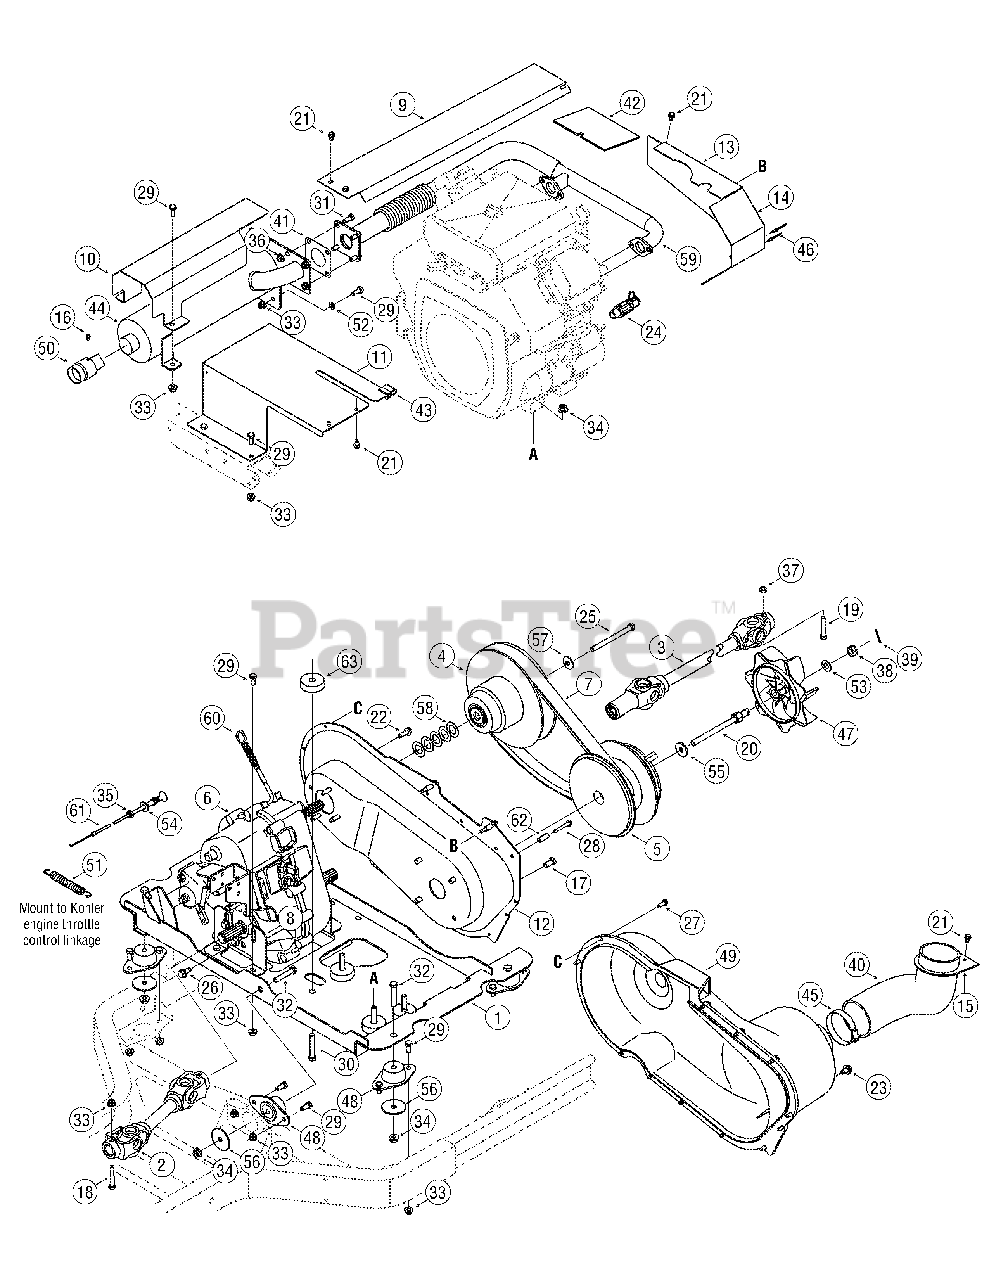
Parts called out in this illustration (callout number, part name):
2	Shaft Asm, Rr/prop
3	Shaft Asm, Frt/prop, Hilliard
4	Clutch Asm, Cvt, Driven
5	Clutch Asm, Cvt, Driver, Cvr
6	Case Asm, Transfer
7	Belt, Cvt, 4x4
9	Cover, Heat, Sheild
10	Exh, Shield, Heat
13	Cover, Eng, Kohler, Sealed Cvt
14	Cover, Engine, Rr, Kohler
16	Screw, F, #8-32, 0.375, Hxindwsh
17	Hex Screw, 3/8-16, .75, Gr5, Std
18	Hex Screw, 5/16-18, 2.00, Gr5, Patch
19	Hex Screw, 5/16-18, 1.875, Gr5, Patch
20	Hex Screw, 7/16-20, 5.00, Gr5, Special
21	Screw, Tt, 1/4-20, 0.500, Hxindwsh
22	Screw, Tt, 5/16-18, 1.000, Hxindwsh
22	Screw, Tt, 5/16-18, .750, Hxindwsh
23	Screw, B, 5/16-12, 0.500, Hxindwsh
24	Drain, Oil
25	Hex Screw, 3/8-24, 4.50, Gr5, Std
26	Screw, Tt, 3/8-16, 0.750, Hxindwsh
27	Screw, Tt, 1/4-20, 0.750, Hxindwsh
28	Screw, Tt, 1/4-20, 1.625, Hxindwsh
29	Hex Screw, 5/16-18, .75, Gr5
30	Hex Screw, 3/8-16, 2.25, Gr5, Std
31	Hex Screw, 5/16-18, .875, Gr5, Std
32	Hex Screw, 3/8-16, 2.00, Gr5, Std
33	Nut, Flglk, 5/16-18, Grf, Nylon
34	Nut, Flglk, 3/8-16, Grf, Nylon
35	Nut, Jam, 3/8-24, Gr5
36	Nut, Flglk, 5/16-18, Gr5, Sd Lk
37	Nut, Hexlk, 5/16-18, Grb, Ctrlk
38	Nut, Hex, 1/2-20, Gr5, Slot
39	Pin, Cot, 3/32, 1.0
40	Tube, Cvt, Intake
41	Gasket, Eng
42	Insl, Frame, Uv
43	Heat Baffle Seal
44	Muffler, Cat/khlr
45	Clamp, Hose, Adj, 2-3/4- 3-3/4
46	Rivet, Pop, .125 Od, #42
47	Impeller, Blo
48	Mount, Comprs, Eng, Hd
49	Cover, Cvt
50	Arrestor Screen, Spark
51	Spring Latch
52	Washer, Flat, .330 X .630 X .0635
53	Washer, Flat, .510 X 1.00 X .060
54	Washer, Flat, .406 X .875 X .059
55	Washer, Flat, .450x1.250x.164, Ht
56	Washer, Flat, .38 X 2.00 X .12
57	Washer, Bell, .396 X 1.140 X .095
58	Washer, Fl, .793x1.368 X.025, Ht
59	Pipe, Exh, Kohl
60	Cable Kit, Throttle, Kohler
61	Cable, Control Choke, Kohler
62	Spacer, .260id X .375od X 1.0l
63	Spacer Engine, Kohler
